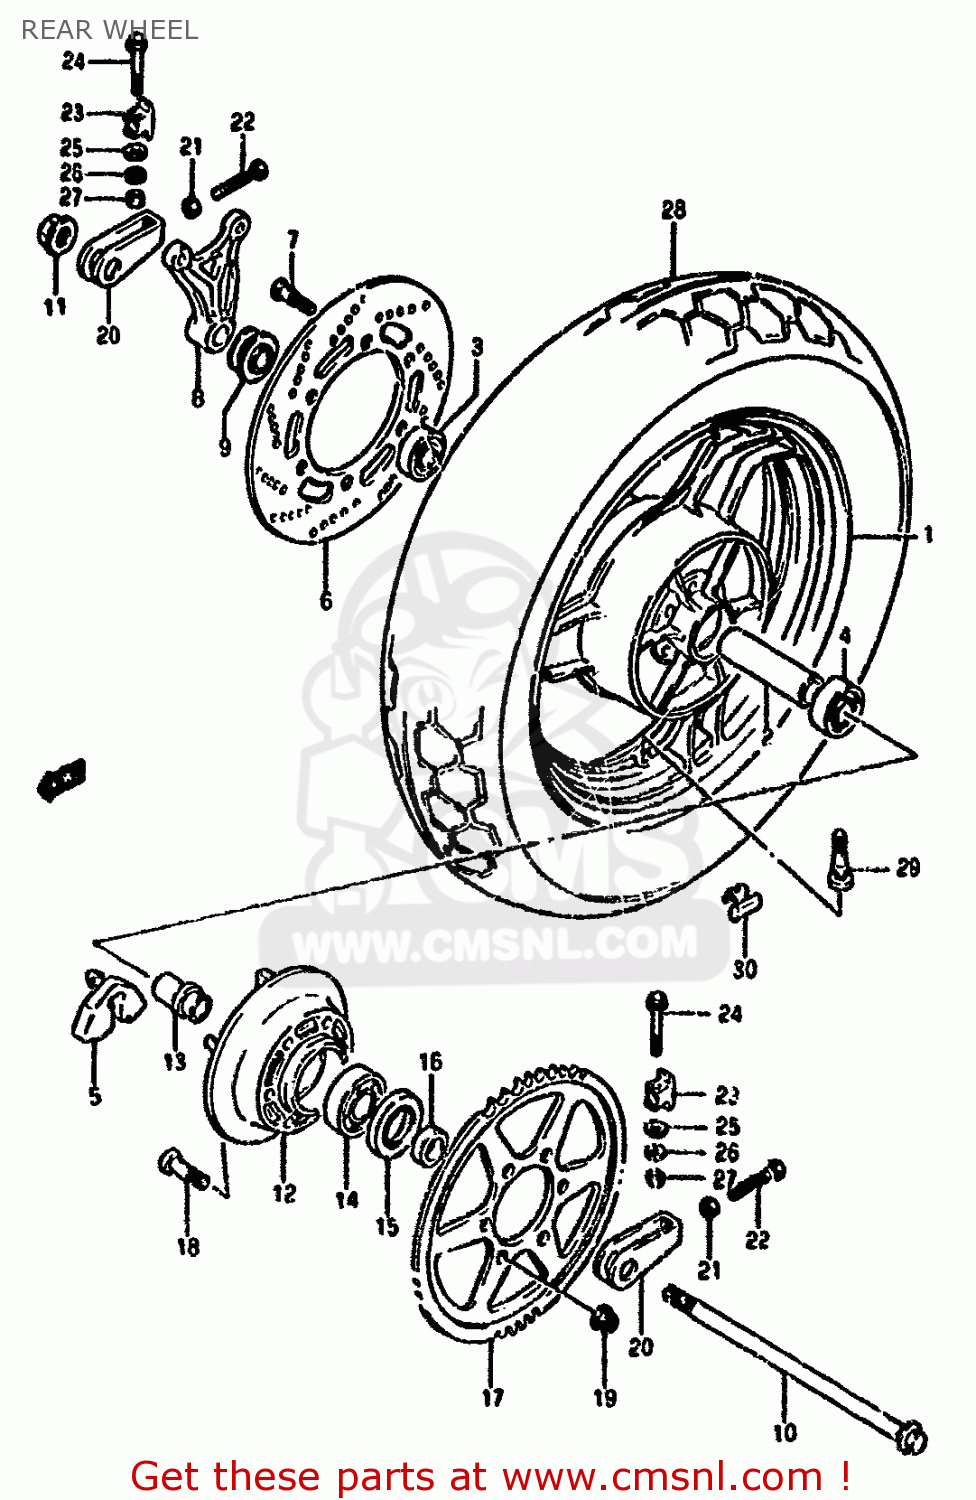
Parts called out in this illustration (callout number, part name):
1	WHEEL,RR(MT,3.50X16)
2	SPACER,REAR WHEEL HUB
3	BEARING
4	BEARING(20X47X14)
5	ABSORBER,RR HUB SHOCK
6	DISC,RR BRAKE
7	BOLT 8X33
8	BRACKET,RR,CALIPER
9	SPACER,RR AXLE,R
10	AXLE,RR
11	NUT ,18MM
12	DRUM,RR SPROCKET MOUNTING
13	RETAINER,RR HUB BEARING
14	BEARING(25X62X17)
15	SEAL,OIL(35X62X8)
16	SPACER,REAR AXLE,LEFT
17	SPROCKET,RR(NT:52)
18	BOLT
19	NUT
20	ADJUSTER,CHAIN
21	NUT
22	BOLT
23	SUPPORTER,CHAIN ADJUST
24	BOLT
25	WASHER
26	WASHER,LOCK
27	NUT
28	TIRE
29	VALVE,TIRE
30	BALANCER,WHEEL
